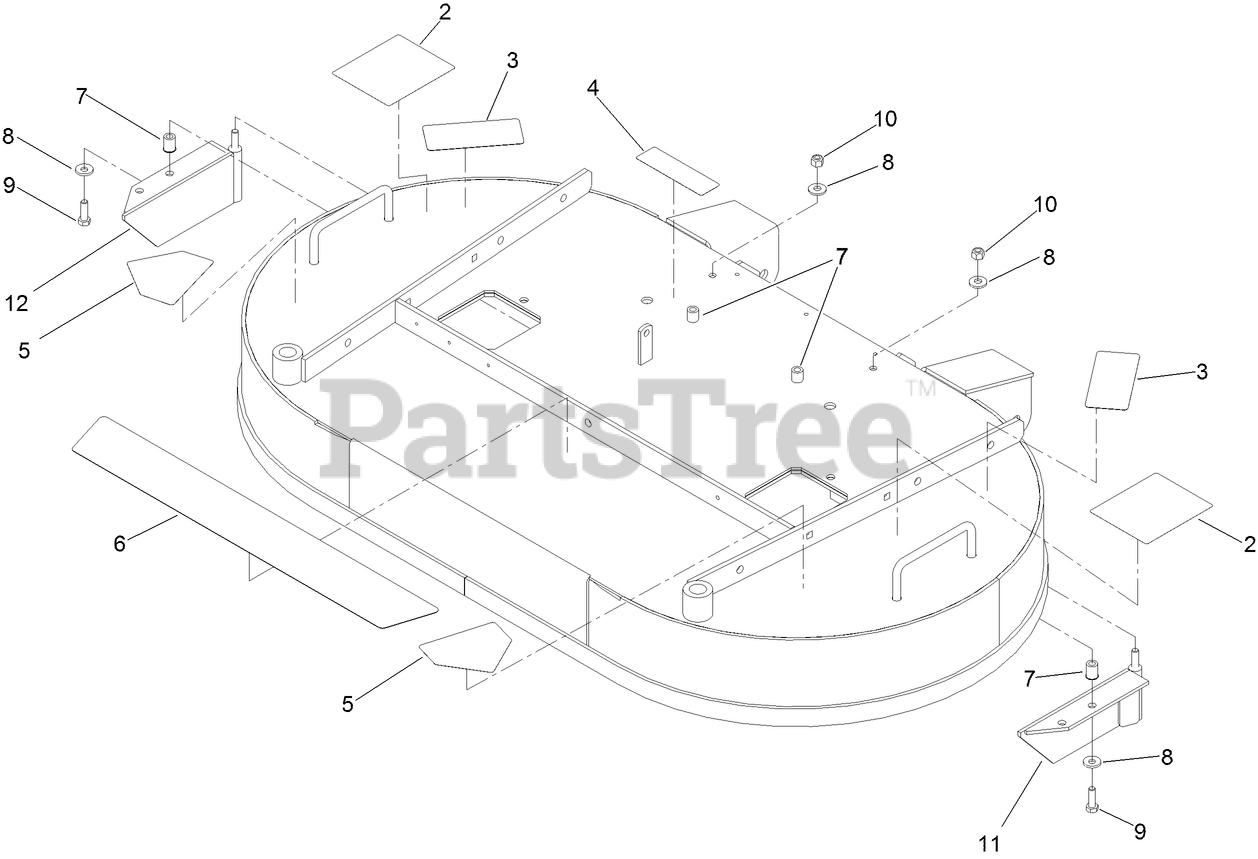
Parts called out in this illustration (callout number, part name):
2	DECAL-HEIGHT ADJUST, CUTTING
3	DECAL-TORQUE, BLADE BOLT
4	DECAL-COVER, MISSING
5	DECAL-DANGER
6	PAD-SKID, ANTI
7	NUT-CLINCH
8	WASHER-SPRING
9	SCREW-HH
10	NUT-LOCK, NI
11	BAFFLE-LH
12	BAFFLE-RH
